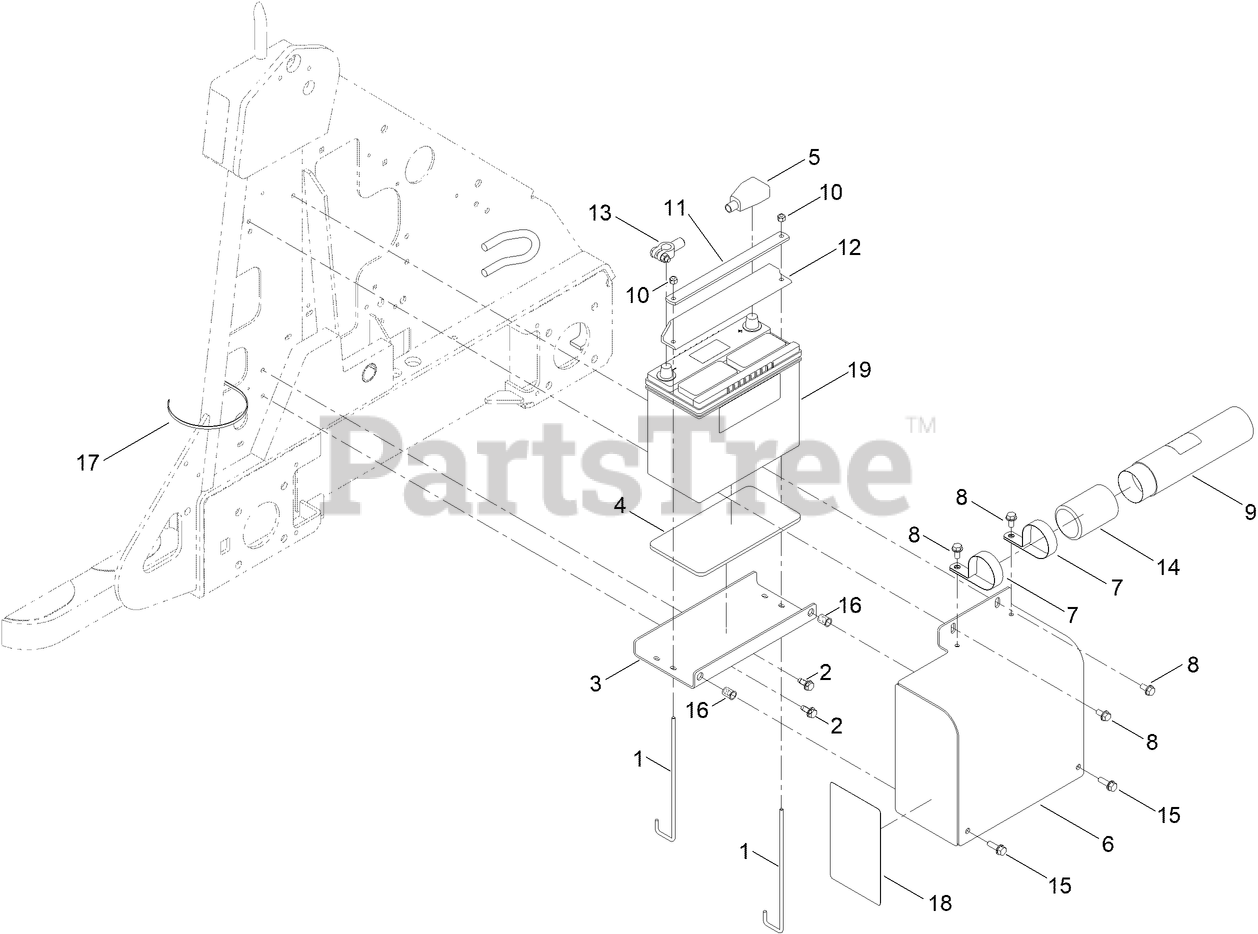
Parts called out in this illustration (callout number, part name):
1	RETAINER-BATTERY
2	SCREW-HWHTF
3	MOUNT-BATTERY
4	PAD-BATTERY
5	CABLE-BATTERY, POSITIVE
6	COVER-BATTERY
7	CLAMP-R
8	SCREW-HWHTF
9	TUBE-MANUAL
10	NUT-LOCK, NI
11	RETAINER-BATTERY
12	RETAINER-BATTERY
13	CABLE-BATTERY, NEGATIVE
14	CAP-HOUSING
15	SCREW-HHF
16	NUT-CLINCH
17	TIE-CABLE
18	DECAL-SERVICE TX320D
18	DECAL-SERVICE TX320D DE
18	DECAL-SERVICE TX320D ES
18	DECAL-SERVICE TX320D FR
18	DECAL-SERVICE TX320D IT
18	DECAL-SERVICE TX320D NE
18	DECAL-SERVICE TX320D PL
18	DECAL-SERVICE TX320D RU
18	DECAL-SERVICE TX320D SK
19	BATTERY-DRY
